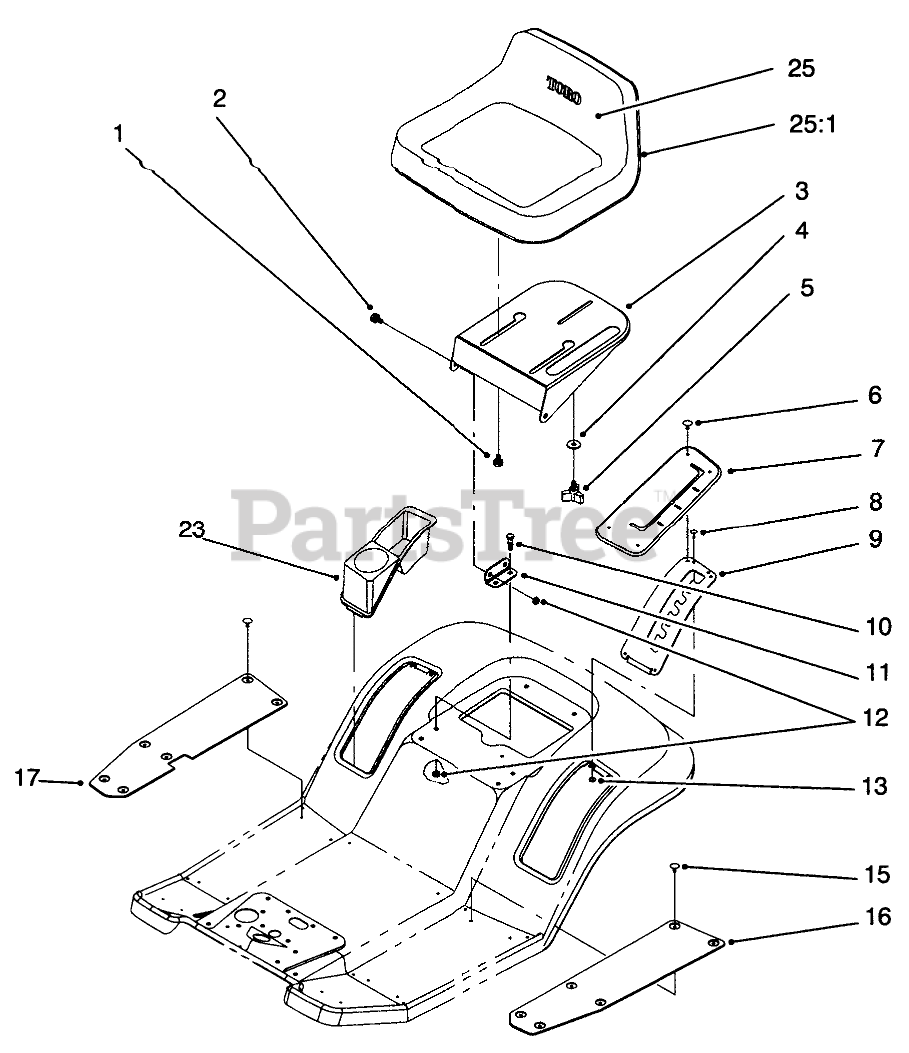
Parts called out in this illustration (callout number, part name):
1	BOLT-SHOULDER
2	BOLT-SHOULDER
3	Support-Seat
4	WASHER-PIVOT
6	FASTENER-PANEL
7	COVER-HOC
8	RIVET-BLIND
9	Gate-H.O.C.
10	SCREW-HH
11	Bracket-Seat Hinge
12	NUT-LOCK, NI
13	WASHER-PLAIN
15	FASTENER-PANEL
16	MAT-FOOT, LH
17	MAT-FOOT, RH
23	TRAY-FENDER
25	Seat-High Back V511 (Incl. Ref. #25:1)
25:1	TRIM - SEAT
